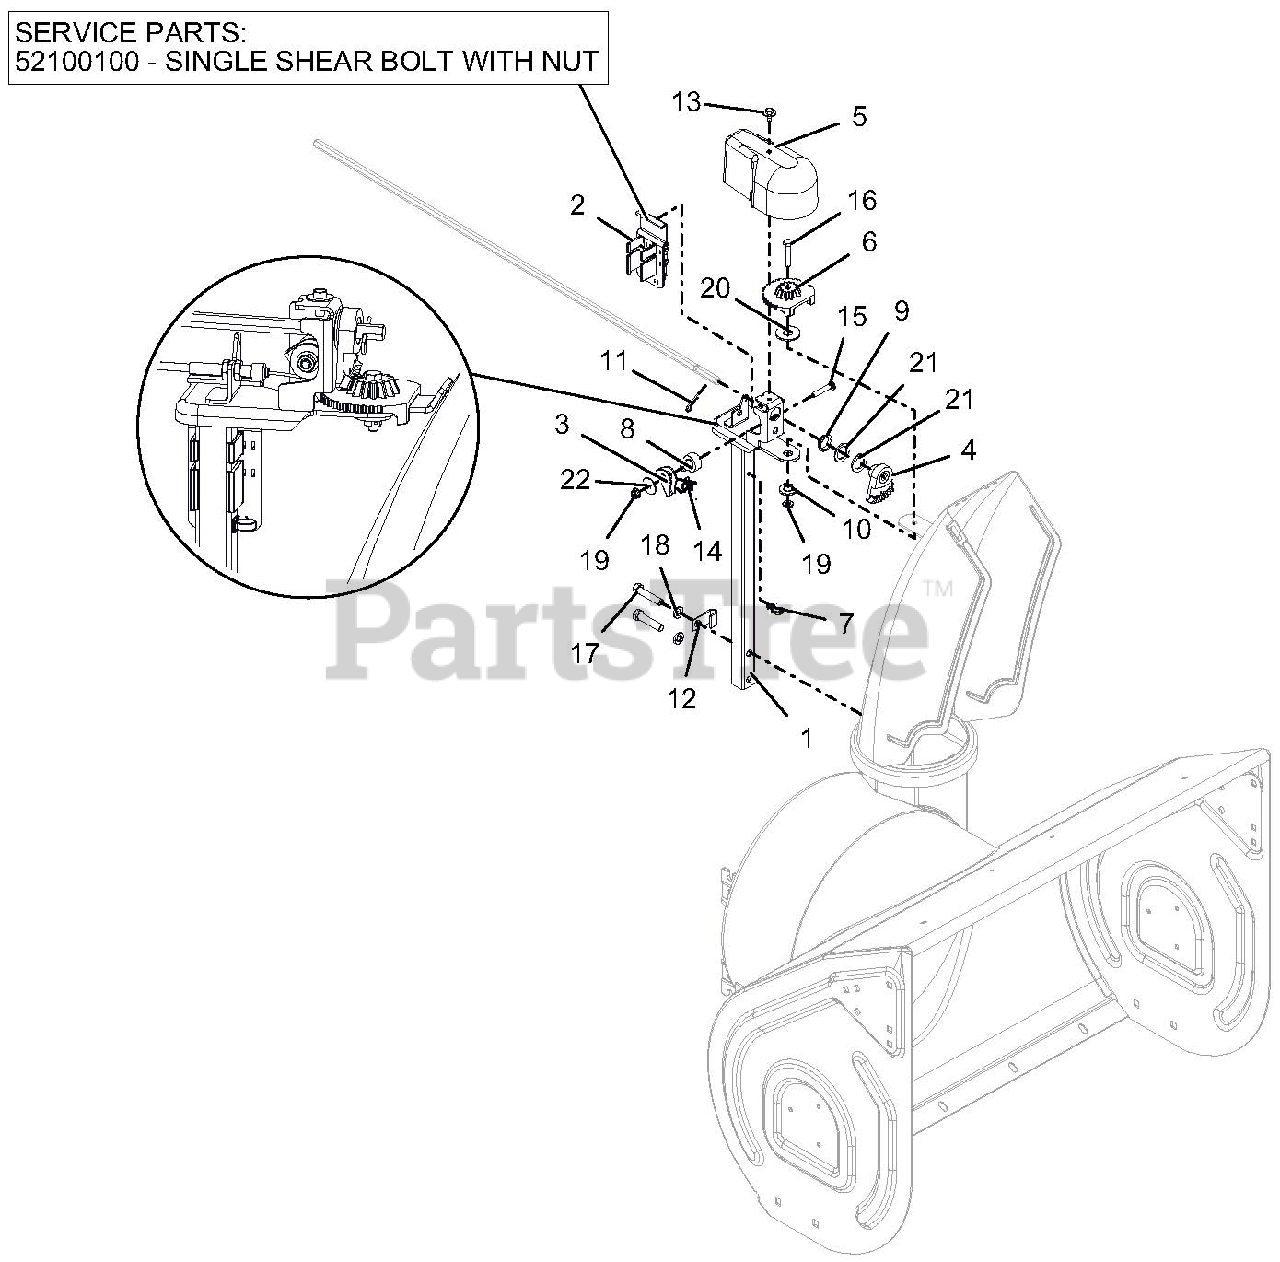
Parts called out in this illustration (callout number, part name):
1	PEDESTAL, CHUTE - QUICK STICK
2	HOLDER W LARGE SHEAR BOLT /NUT
2	SHEAR BOLT SERVICE ASSEMBLY
3	ARM, LOCKING
4	GEAR, CHUTE-ACTUATION
5	COVER, CHUTE GEAR
6	GEAR, CHUTE
7	CLIP, CABLE GUIDE
8	BUSHING, LOCK ARM
9	BUSHING, POLYLINER-.75 SNAPIN
10	BSHG-FLG .265X.477X.375X1.00
11	PIN-HAIR INT .08X.18X1.18 YWZC
12	J-CLAMP
13	SCR-TAP .25-20X.50 LGHWH TR YZ
14	SG-TORS
15	@BLT-RDHDSQNK .25-20X1.50 G5YZ
16	@BLT-HEX .25-20X1.50 GR5 YWZC
17	@BLT-HEX .38-16X1.75 GR5 YWZC
18	@WSHR-LK .38X.094 REG YWZC
19	@NUT-LK-CTR-FLG .25-20 YWZC
20	WSHR-FLT-NYL .515X1.375X.093
21	WSHR-FL-STL.754X1.125X.062YWZC
22	WSHR-FL-STL .281X1.000X.063
